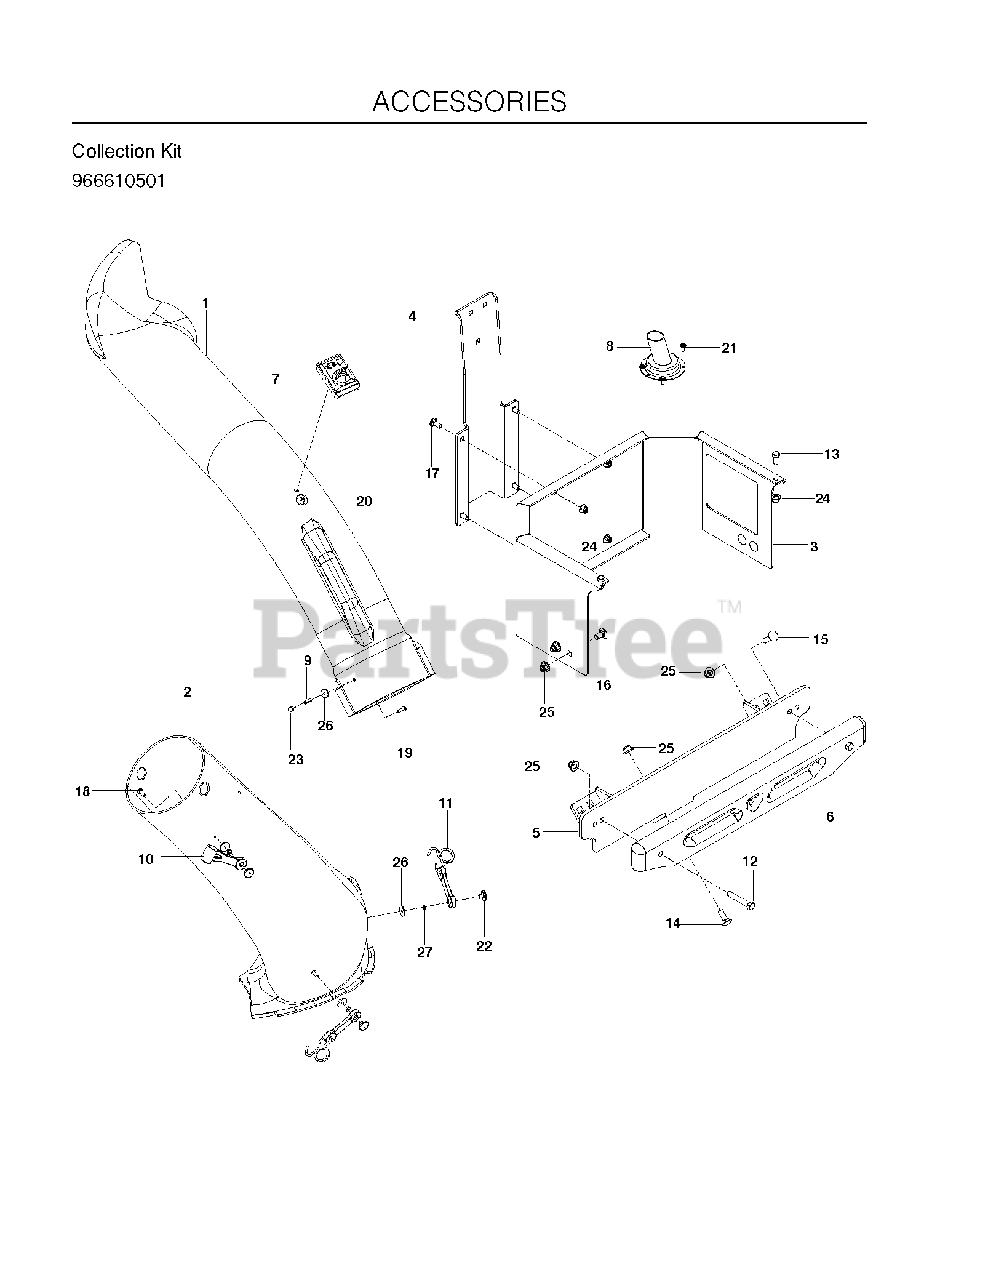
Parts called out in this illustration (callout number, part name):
1	UPPER CHUTE
2	BOOT, LOWER 42
4	BRACKET, COLLECTION (PTD)
5	WLDMT, WEIGHT BRKT RZ30 PTD
6	WEIGHT, CAST
7	DUMP BAG INDICATOR
8	MUFFLER EXTENSION
9	SPACER LT
11	LATCH ASSY
12	HCS 3/8C X 2 1/4
14	RHSNB 3/8C X 1
15	RHSNB 3/8-16 X 1-1/4
16	RHSNB 3/8-16 X 3/4 GR5 ZD
17	BOLT 5/16C X 3/4" CARRIAGE
18	SCREW #10-24 X 5/8
19	SCREW #10-24 X 1-1/8 ZD SPEC
20	SCREW
21	SCREW, TAP #10-16 X 1/2
24	5/16-18 NYLOC FLANGE NUT
25	NUT 3/8-16 HEX FLG NYLOC ZD
27	WASHER - 3/8
